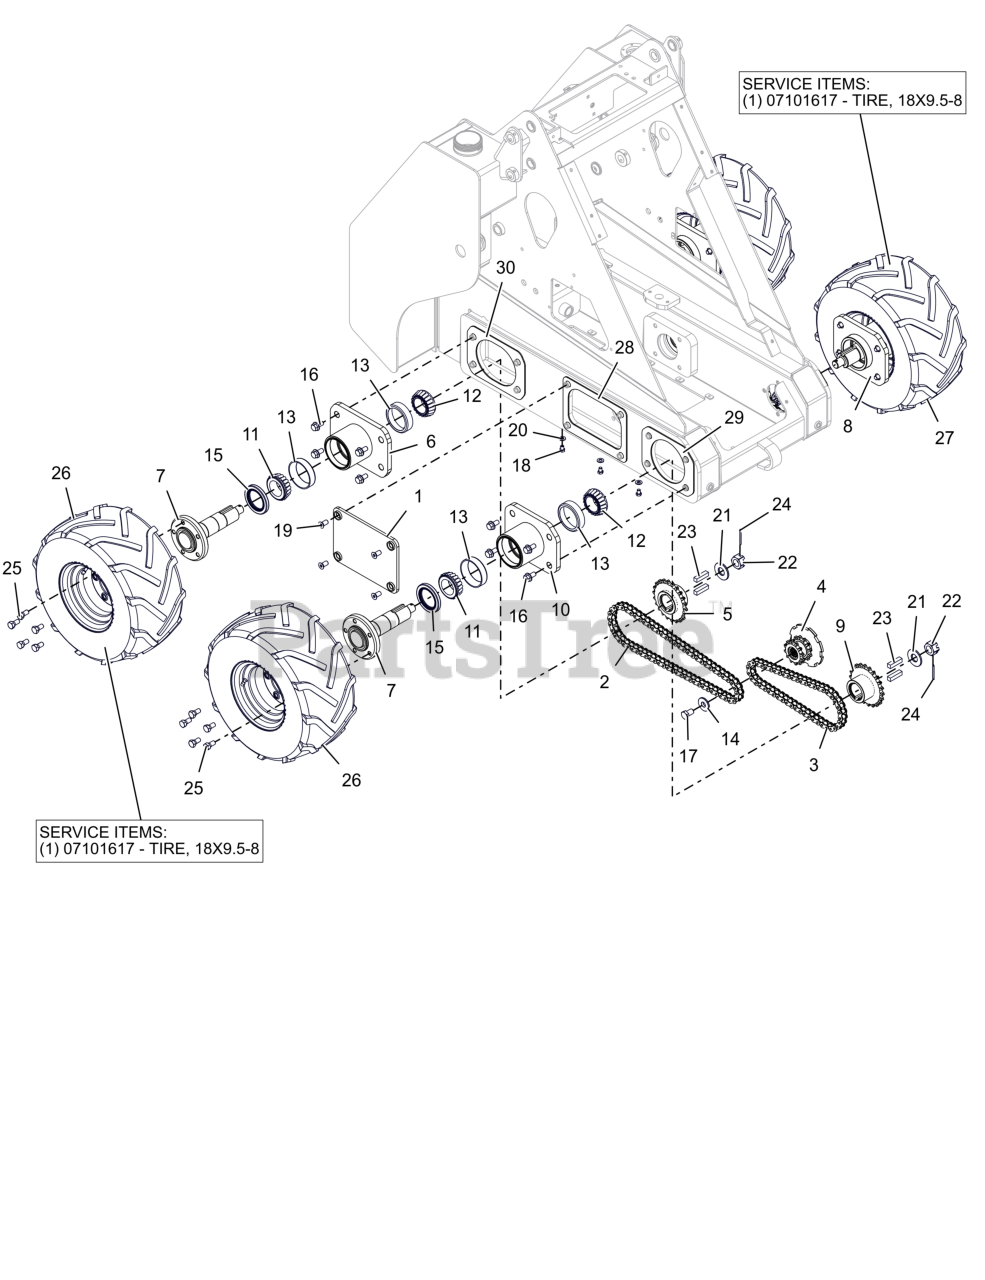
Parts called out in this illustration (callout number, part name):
1	COVER, TRANSMISSION (RED)
2	CHAIN, ROLLER -RS60HT 64 PITCH
3	CHAIN, ROLLER -RS60HT 48 PITCH
4	SPROCKET, DRIVE - DW
5	SPROCKET, DRIVEN -REAR #60 22T
6	WLDMT, HUB -REAR WHEEL
7	WLDMT, AXLE - WHEEL
8	WLDMT, HUB -FRONT LH WHEEL
9	SPROCKET, DRIVEN -FRONT #60 22T
10	WLDMT, HUB -FRONT RH WHEEL
11	BRG, CONE 2.063 X 1.193
12	BRG, CONE 2.000 X 1.193
13	BRG, CUP 3.672 X .938
14	SPCR, FLANGE
15	SEAL, OIL - 2.50X3.756X.500
16	BLT, HEX-FLG 0.5-13X1 GR8 ZCC
17	BLT, HEX 0.625-18X1 GR5 ZCC
18	@BLT-HEX .38-16X.50 GR5 YWZC
19	SCR, MCH .50-13X1.00 SFH ZCC
20	WSHR,FLT .406X.812X.065 ZCC
21	WSHR, FLAT - HRD 1.01X2.25X.19
22	NUT, SLOTTED-1.00-14
23	KEY-SQ - .500x2.000
24	PIN, CTR .18X2.00 EXTPRSQCT ZCC
25	BLT-LUG .50-20X1.38 YWZC
26	ASSM TIRE\WHEEL, BAR 18X 9.5 - 8 RH
26	TIRE, BAR 18X9.5 - 8 K357
27	ASSM TIRE\WHEEL, BAR 18X 9.5 - 8 LH
27	TIRE, BAR 18X9.5 - 8 K357
28	GASKET, ACCESS TRANSMISSION
29	GASKET, FRONT TRANSMISSION
30	GASKET, REAR TRANSMISSION
